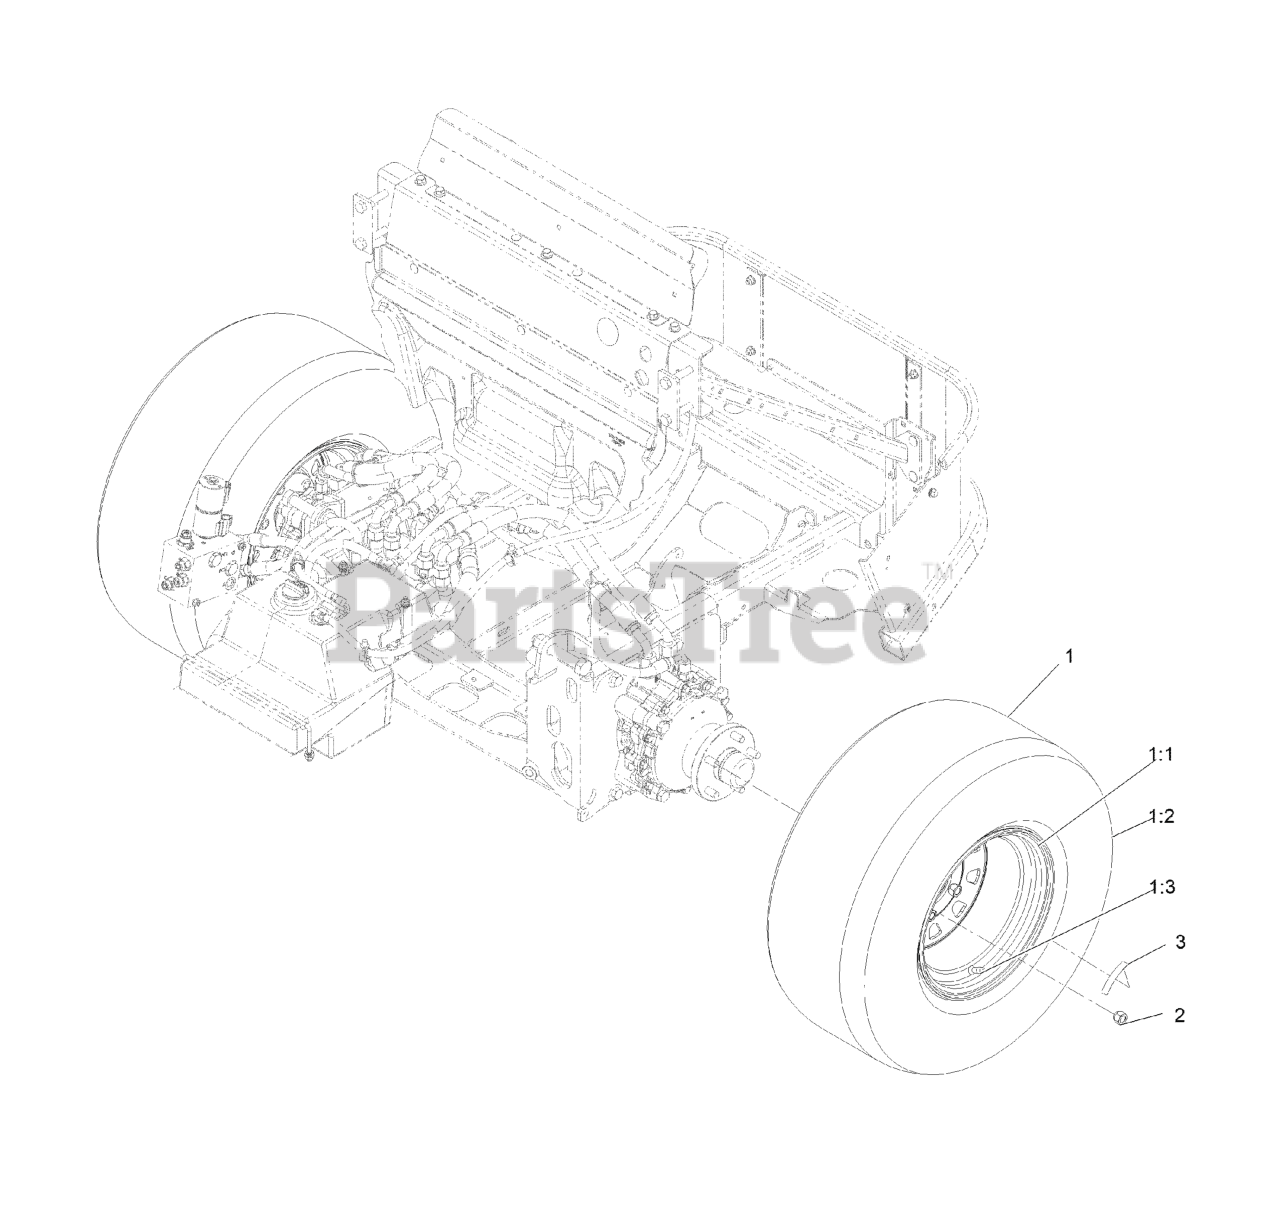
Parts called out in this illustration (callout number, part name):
1	ASM-TIRE 26X12-12, 1.0 OFFSET
1:1	RIM ASM, 1.0 OFFSET
1:3	Stem-Valve
2	NUT-LUG
3	DECAL-TORQUE, WHEEL NUT
